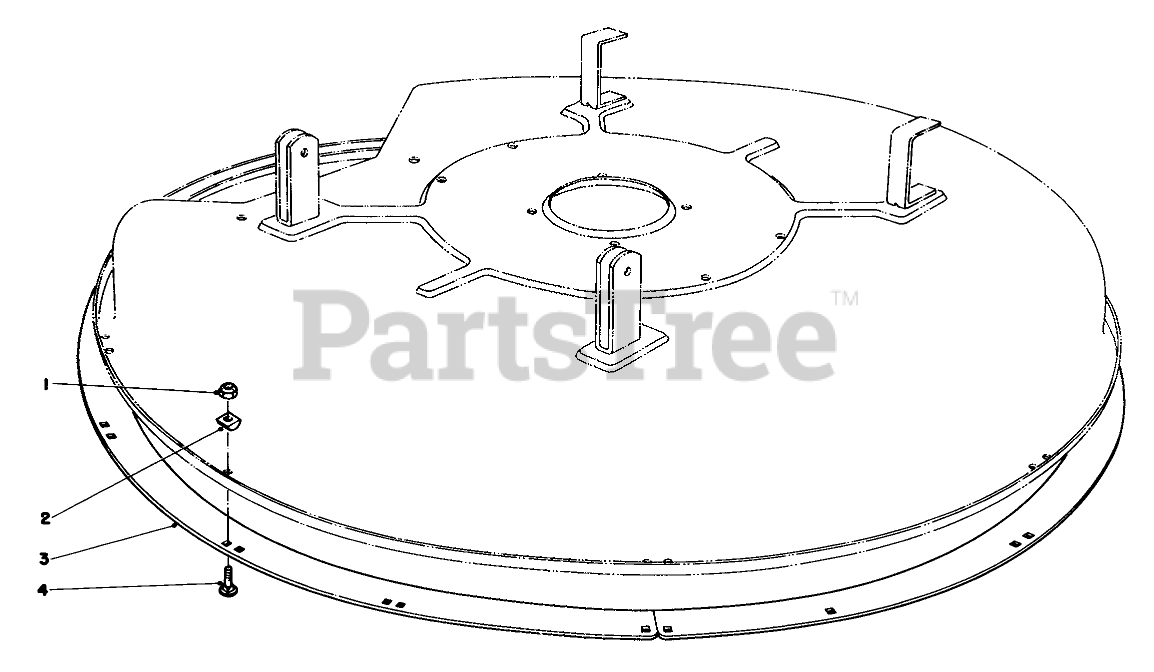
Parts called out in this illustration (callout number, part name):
1	NUT-LOCK, NI
2	Spacer-Deck Ring
3	DECK RING B
4	BOLT-CARR
